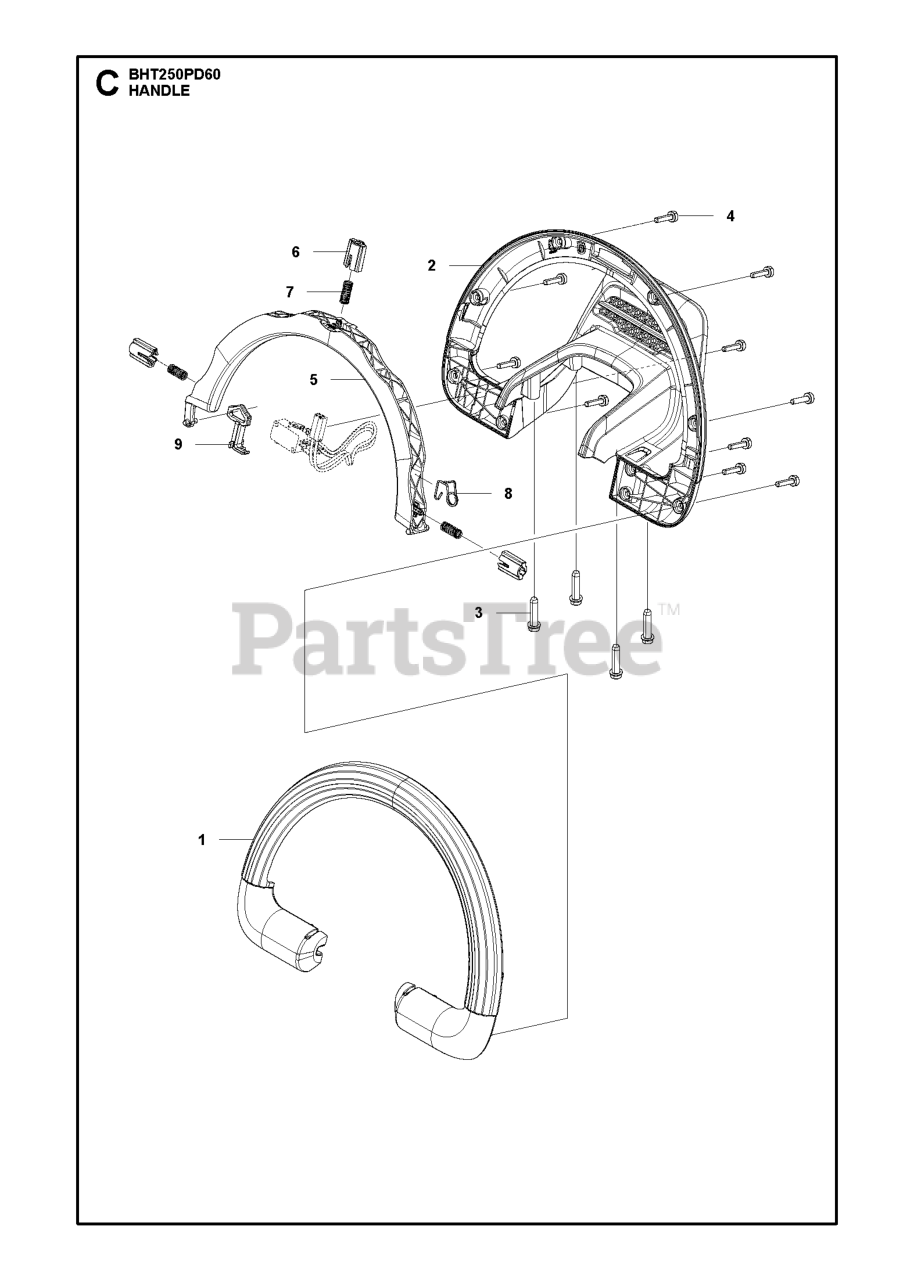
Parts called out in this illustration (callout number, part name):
1	FRONT HANDLE COVER BLACK
2	FRONT HANDLE HANDGUARD BLACK
5	FRONT HANDLE LOCK OUT
6	BUSHING FRONT HANDLE
7	RECOIL SPRING FRONT HANDLE
8	SPRING FRONT HANDLE
9	LEVER FRONT HANDLE
